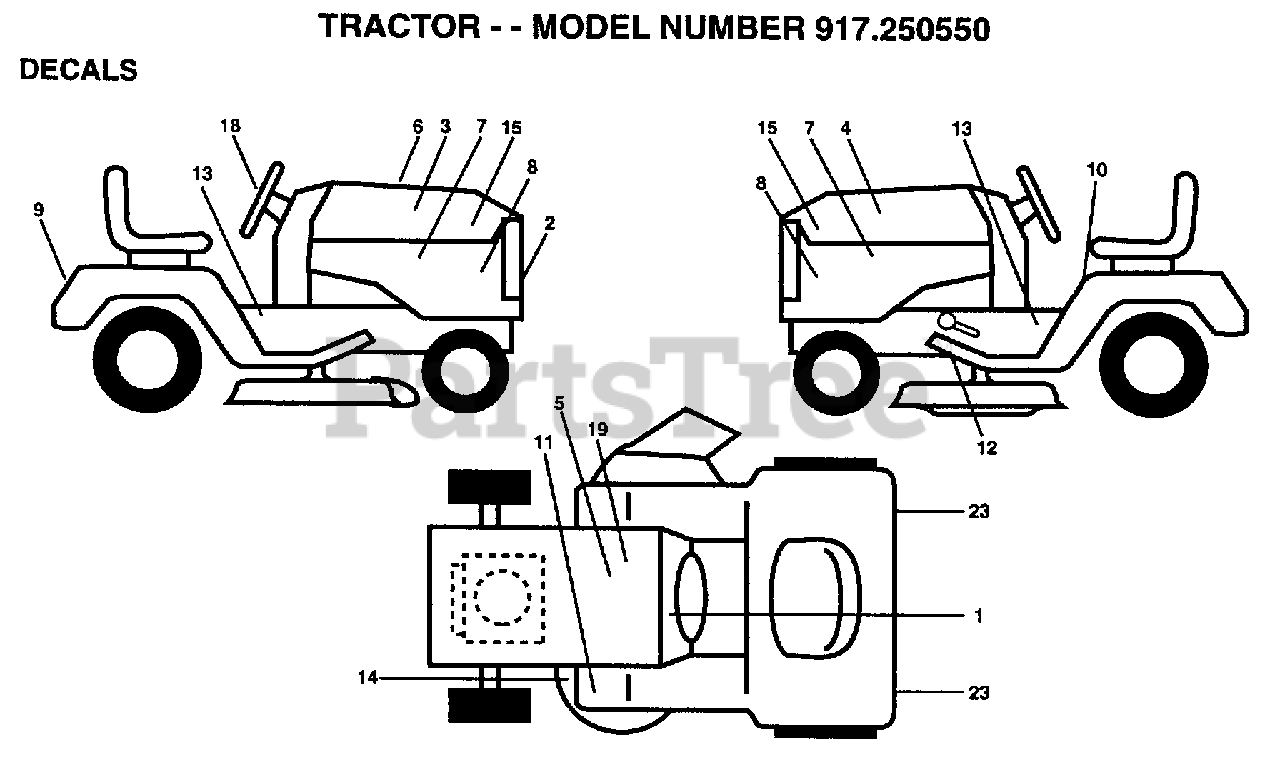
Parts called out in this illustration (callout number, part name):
1	DECAL.DASH.INST.
2	DECAL.GRILLE.HDGT
3	DECAL.HOOD.RH
4	DECAL.HOOD.LH
5	DECAL.BTRY.SRS.EN
6	DECAL
7	DECAL.PANEL.SIDE
8	DECAL.SIDE.PANEL
12	DECAL.V-BELT.DRV
14	"DECAL.V.BELT.44"""
18	DECAL.INS.STRG.WH
19	DECAL.BATTERY
23	REFLECTOR-TAIL YT
